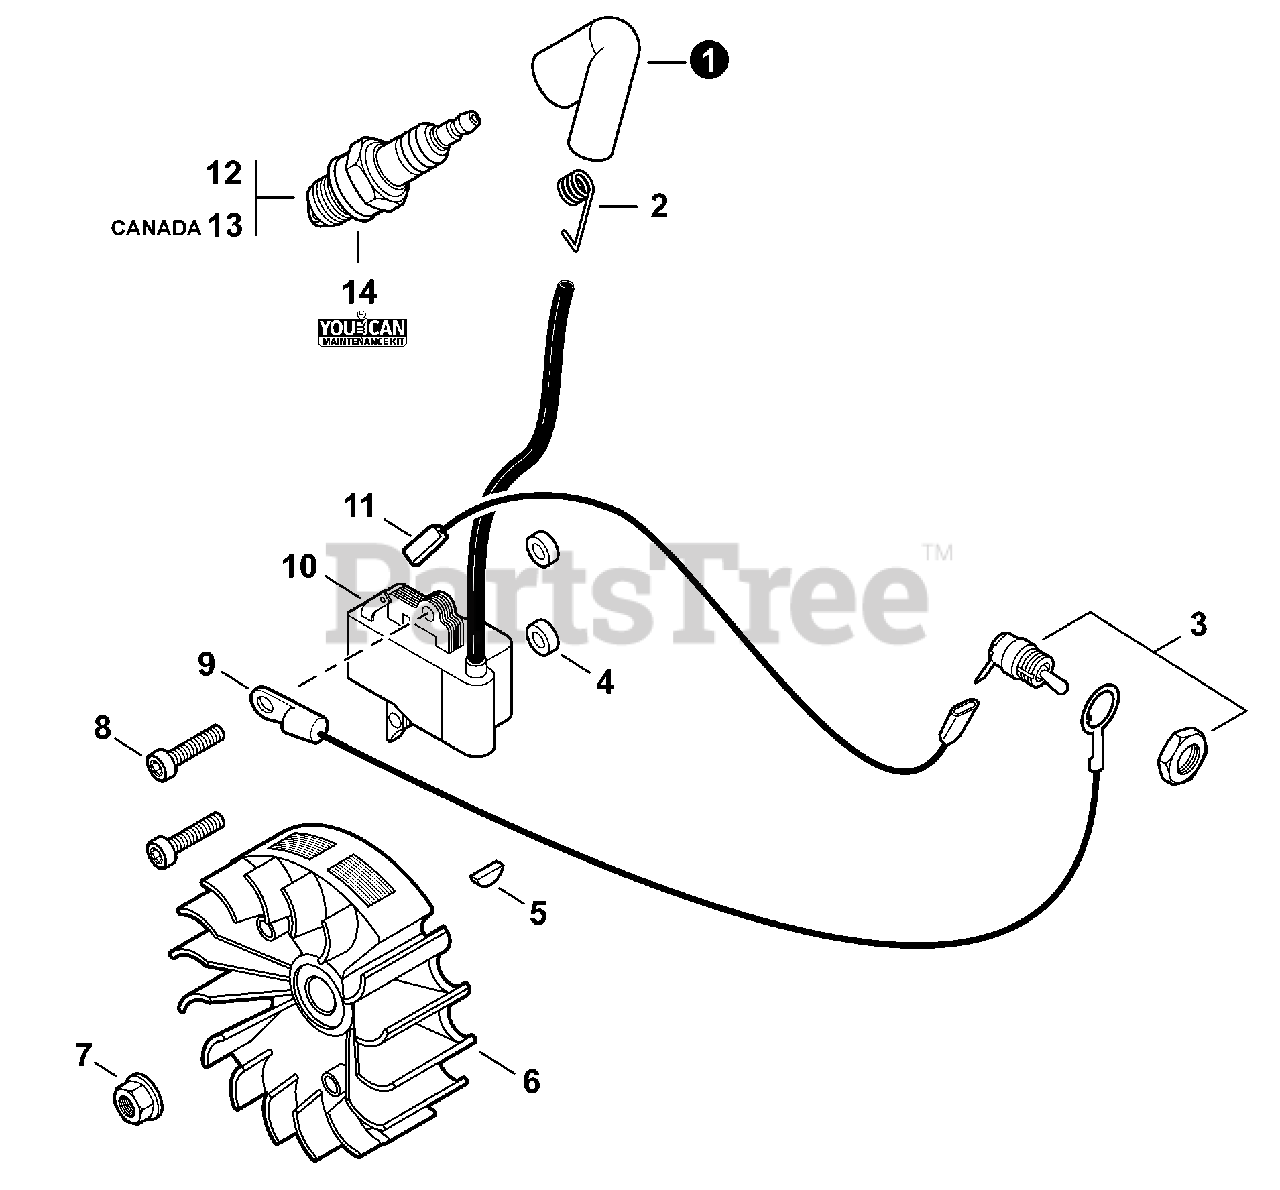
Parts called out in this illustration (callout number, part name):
1	CAP, SPARK PLUG
2	TERMINAL, SPARK PLUG
3	SWITCH, ON-OFF
4	WASHER 5.2×12×3
5	KEY, WOODRUFF
6	FLYWHEEL
7	NUT, FLANGE M8
8	BOLT, TORX 5×20
9	LEAD - GROUND L= 255
10	COIL, IGNITION
11	LEAD - IGNITION
12	SPARK PLUG - BPM8Y
13	SPARK PLUG - BPMR8Y
14	TUNE-UP KIT - YOUCANT
